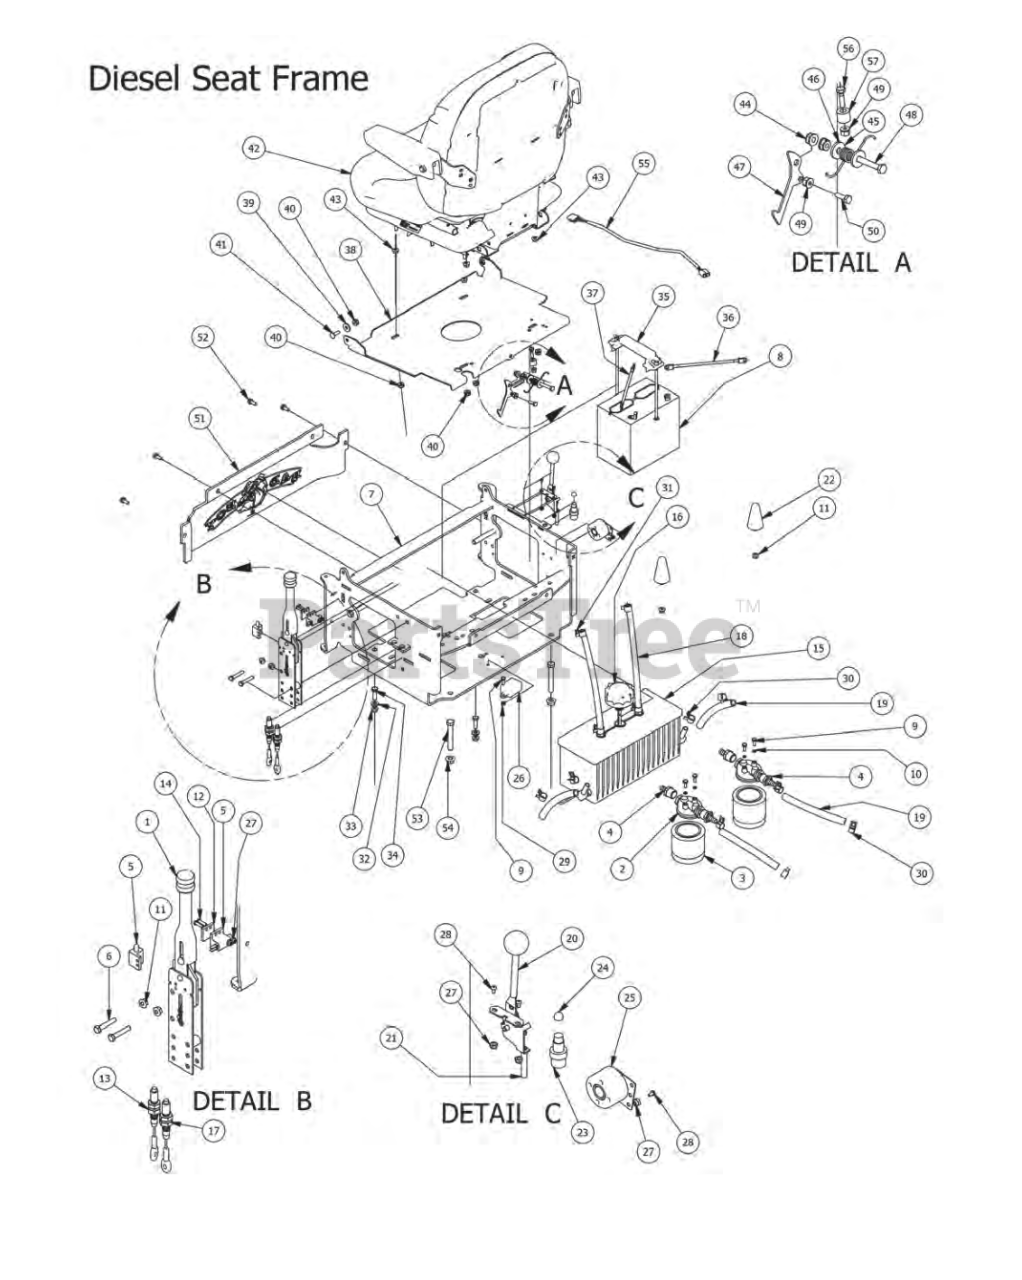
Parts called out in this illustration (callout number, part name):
1	Hand Brake Assembly
2	Filter Head
3	Hydraulic filter
4	Filter Head Fitting
6	5/16" x 1 3/4" Hex Bolt
7	2007 Diesel Seat Frame
8	Battery - Diesel Models - 151
9	1/4" x 3/4" Hex Bolt
10	1/4" Lock Washer
11	5/16" Flange Nut w/Serrations
12	Switch Block Plastic
13	Short Brake Cable
14	1024 x 1" Allenhead Bolt
15	Aluminum Hydraulic Tank
16	Hydraulic Tank Cap
17	Long Brake Cable
18	3/8" x 32" Clear Hose
19	1/2" x 9 1/4" Braided Hose
20	Throttle- Diesel
21	Diesel Throttle Cable Only
22	Spring Cushion
23	Momentary Start Switch
24	Start Switch Boot-Diesel
25	Heat Warning Piezo Buzzer
26	Auto Shut Down for Cat Diesels
27	#10 Nylock Nut
28	1024 X 5/8" Buttonhead Bolt
29	1/4" Hex Nut
30	1/2 Hose Clamp
31	3/8 hose clamp
32	3/8" Flat Washer
33	3/8" Flange Nut
34	3/8" x 1 1/4" Hex Bolt
35	Battery Hold Down
36	Black Battery Cable - Diesel
37	Red Battery Cable - Diesel
38	2006 Seat Plate
39	360 ID Plastic Washer
40	5/16-18 Nylon Flange Nut
41	5/16" x 1" Carriage Bolt
42	Grammer Suspension Seat
43	5/16" Flange Nut
44	5/16-18 Nylon Flange Nut
45	Torsion Spring for Seat latch
46	.360 ID Plastic Washer
47	Seat Latch Lever
48	5/16-18 X 2 Hex C/S (GR.5) ZC
49	1/4-20 Nylon Insert flange Nut
50	1/4-20 x 1-1/4 GR 5 Hex Bolt
51	Cooler Cover
52	5/16 x 3/4 washer head type F screw
53	1/2 x 3 1/2 Flange Bolt Grade 8
54	1/2" Flange Nut
55	Seat Switch Adapter
56	1/4-20 x 1 GR 5 hex bolt zinc
57	380x.735x.470 Nylon Spacer
